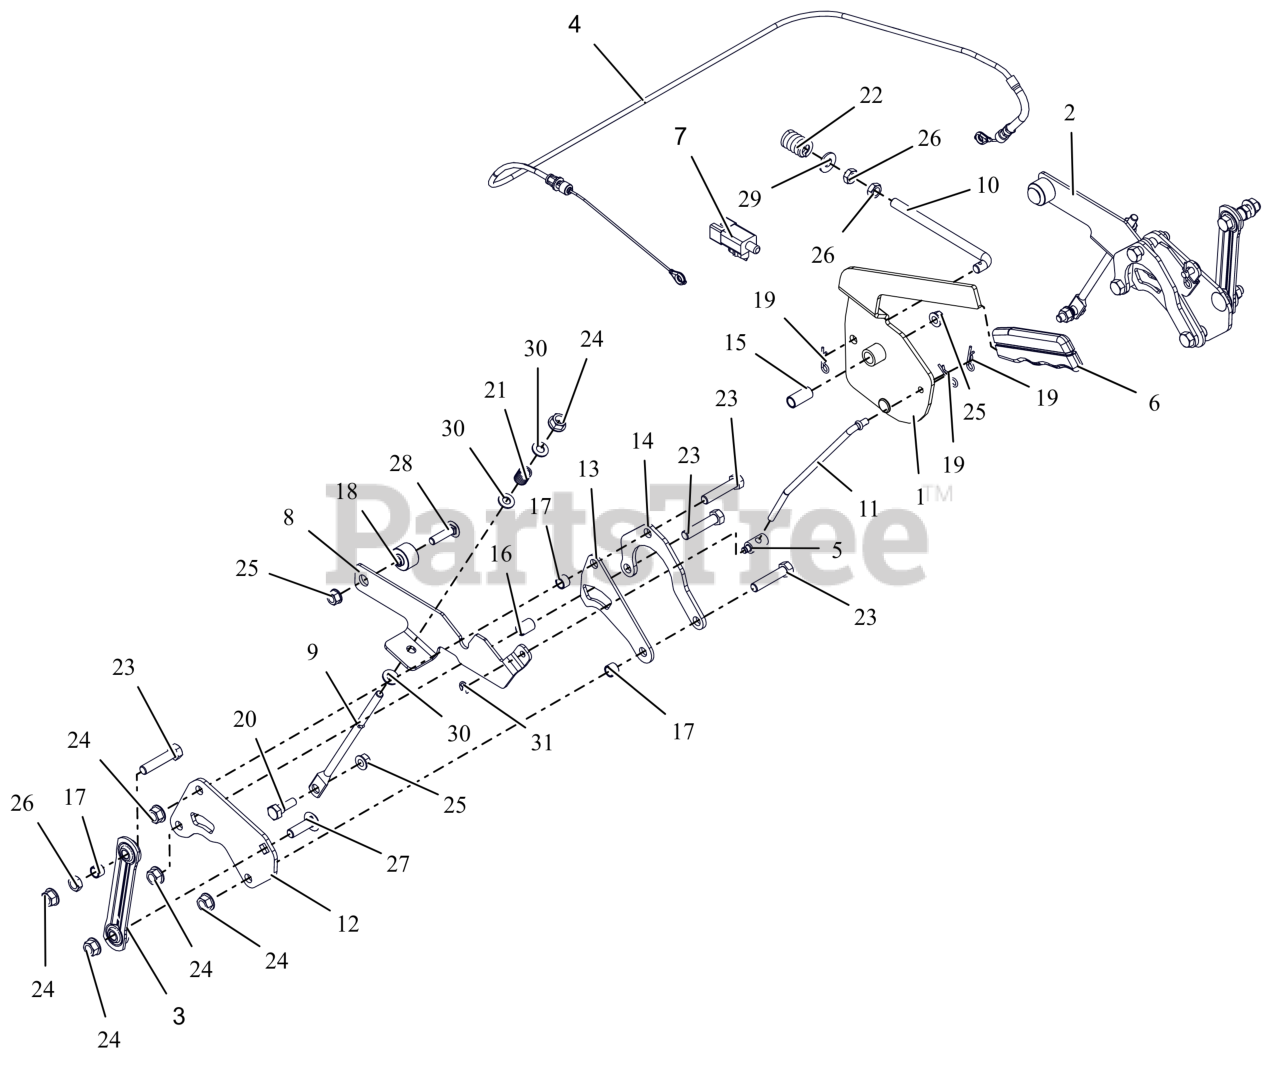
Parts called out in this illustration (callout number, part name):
1	LEVER, PARKING BRAKE
2	ARM, BRAKE - LH (W/PIN)
3	LINK, STAMPED STEERING
4	CABLE, BRAKE - PARKING
5	TRUNION, 1/4-20
6	GRIP, PARKING BRAKE (YELLOW)
7	SWITCH, SNAP IN - N.O./N.O.
8	ARM, BRAKE-RH
9	ROD, LINK - TRANSMISSION BRAKE
10	ROD, OVER CENTER
11	ROD, BRAKE LINK
12	BRKT, TRANSAXLE STEERING
13	BRKT-SPACER
14	PLATE, REAR REINFORCING
15	BSHG-SLV .385X.500X1.045
16	SPCR, SLV .385X.500X.652
17	SPCR, SLV .385X.500X.350
18	SPCR, FLANGE
19	PIN, HAIR #213 .08X1.19 ZCC
20	BOLT,SHLDR .38X.25 -.31-18X.75
21	SPRING, COMPRESSION
22	SG-COMP .187X.56X1.62
23	BLT, HEX .38-16X1.75 G5 ZCC
24	NUT-LK-TOP-FLG .38-16 ZC120
25	NUT-LK-TOP-FLG .312-18 GF ZCC
26	NUT-JAM .375-16 G2 ZCC
27	BLT,RHSSN .38-16X1.25 G5 ZCC
28	BTL,RHSSN .313-18 X 1.25 G5 ZCC
29	WSHR,FLT .375X.875X.083 ZCC
30	WSHR,FLT .344X.688X.065 ZCC
31	RG-RTNG-EXT .250X.025
